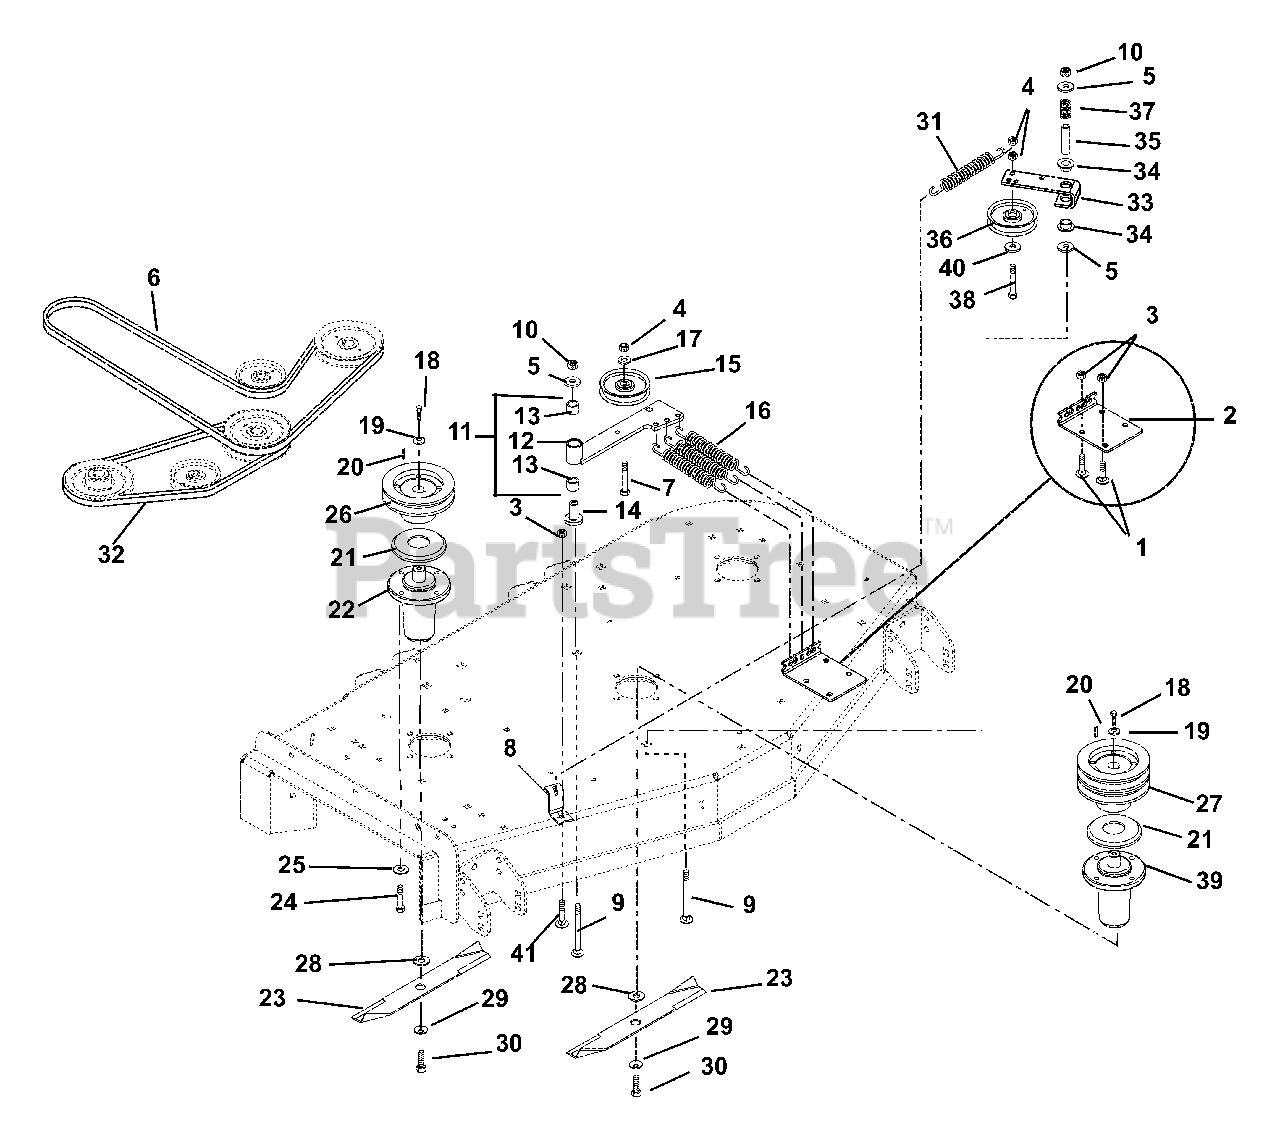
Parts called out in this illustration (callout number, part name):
1	@BLT-RDHDSQNK .38-16X.75 G5YZ
2	BRACKET,LONG SPRING (DIESEL)
3	@NUT-LK-TOP-FLG .38-16 YWZC
4	@NUT-LK-CTR .38-16 YWZC
5	@WSHR-FL-STL.50X1.25X.083 YWZC
6	V-BELT, HB-WRAPPED
7	@BLT-RDHDSQNK .38-16X2.75 G5YZ
8	ANCHOR, SPRING (RED)
9	@BLT-RHDSSQNK .50-13X3.50 G5YZ
10	@NUT-LK-TOP-FLG .50-13 YWZC
11	ASSY-DECK IDLER PIVOT ARM
12	WMT, DECK IDLER PIVOT ARM
13	BRG, 1.00 X 1.12 X .75
14	BEARING, PEDESTAL
15	IDLER-FLAT 4.00 X .38 (2.32W)
16	SPRING, EXT0NSION DIA1.0X6.0LG
17	WSHR-FL-STL .375X1.125X.065YWZ
18	BLT-HEX .38-16X1.00 YZ GR8
19	WASHER, CUPPED SERRATED, .375
20	KEY, SQ .25X.25X1.00 RC 40-50
21	SLINGER, DUST
22	ASM,MAINT FREE SPINDLE
23	BLADE 60" MOWER CE
23	BLADE, MULCHING (20.50")
24	@BLT-HEX .38-16X1.00 GR5 YWZC
25	@WSHR-LK .38X.094 REG YWZC
26	WELDMENT, SPINDLE SHEAVE 6.00
27	SHEAVE, DOUBLE (6.25")
28	WSHR-FLT .640X1.75X.250 YWZC
29	WSHR-BLVL .669X1.535X.138
30	BLT-HEX .62-18X1.75 GR8 YWZC
31	SPRING, EXT
32	V-BELT, HB-RAW EDGE
33	ARM,IDLER PIVOT
34	BSHG-FLG .762X1.0X.580X1.48 NY
35	SPACER .560X.750X2.437 ST
36	V-IDLER, 4.00X.38
37	SG-COMP .085X.80X1.00 WLD36
38	@BLT-HEX .38-16X2.25 GR5 YWZC
39	ASM,MAINT FREE SPINDLE
40	@WSHR-FL-STL.406X.812X.065 YWZ
41	@BLT-RDHDSQNK .38-16X1.00 G5YZ
